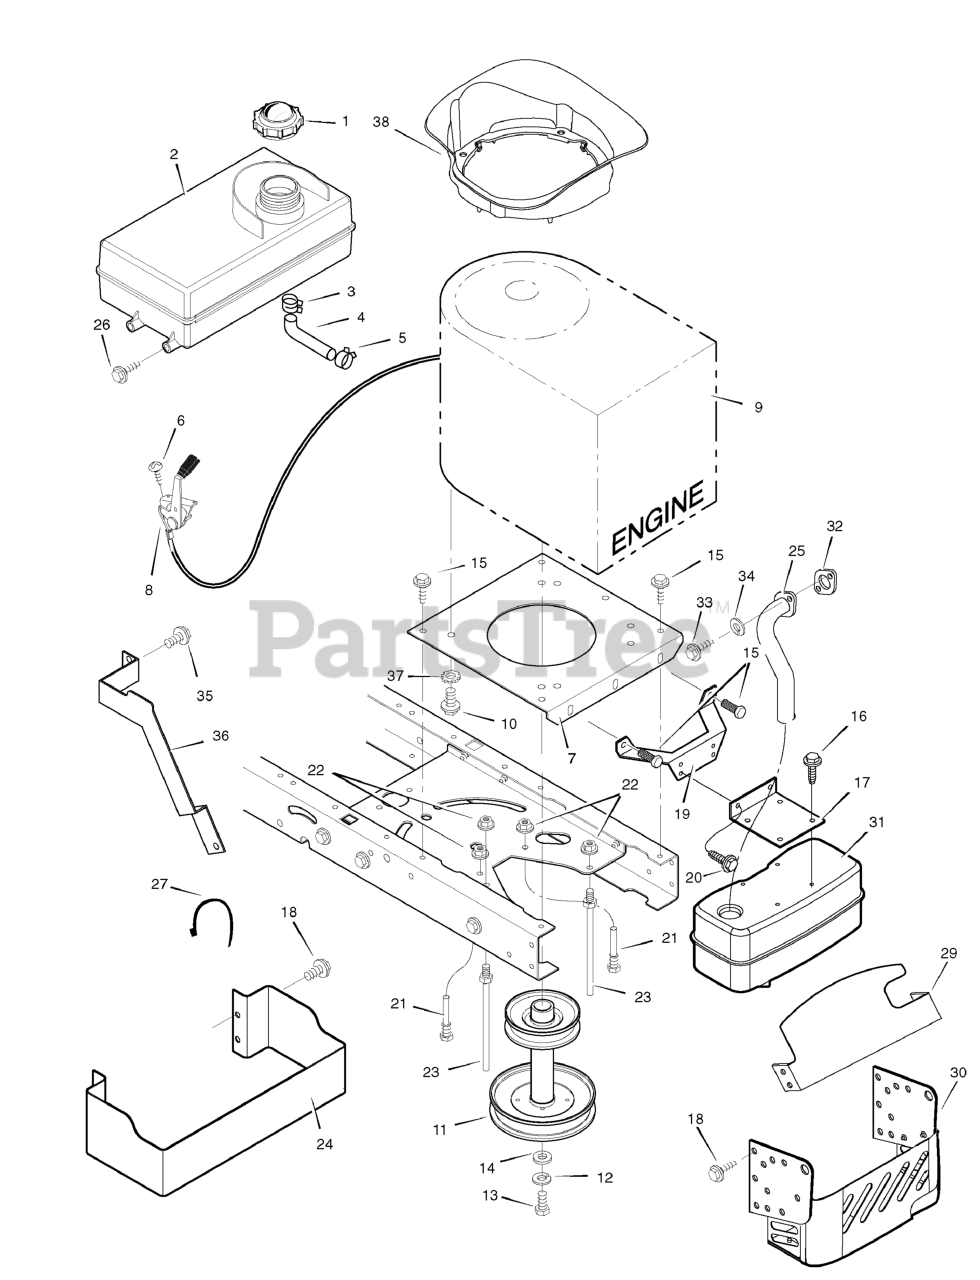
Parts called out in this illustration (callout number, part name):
1	Fuel Cap
2	TANK, Fuel 1.4 Gal.
3	Hose Clamp
4	Fuel Line (Must cut to length)
5	Hose Clamp
7	Plate, Engine
8	Throttle Control
9	Engine, Briggs & Stratton *
10	Bolt, Engine Mount
11	STACK PULLEY ASSEMBLY
12	Lockwasher
13	Bolt, Hex
17	Bracket, Muffler
19	Bracket, Muffler Mount
21	Guide, Belt
22	Nut, Flange
23	Guide, Belt
24	GUARD, Heat Shield
25	Exhaust Tube, Single
27	Tie Strap
29	HEAT SHIELD, Upper
30	Shield, Heat
31	Muffler
32	Gasket
34	Washer
35	Bolt, Washer Hex Head
36	Guard, Exhaust Pipe
37	Washer, Star
